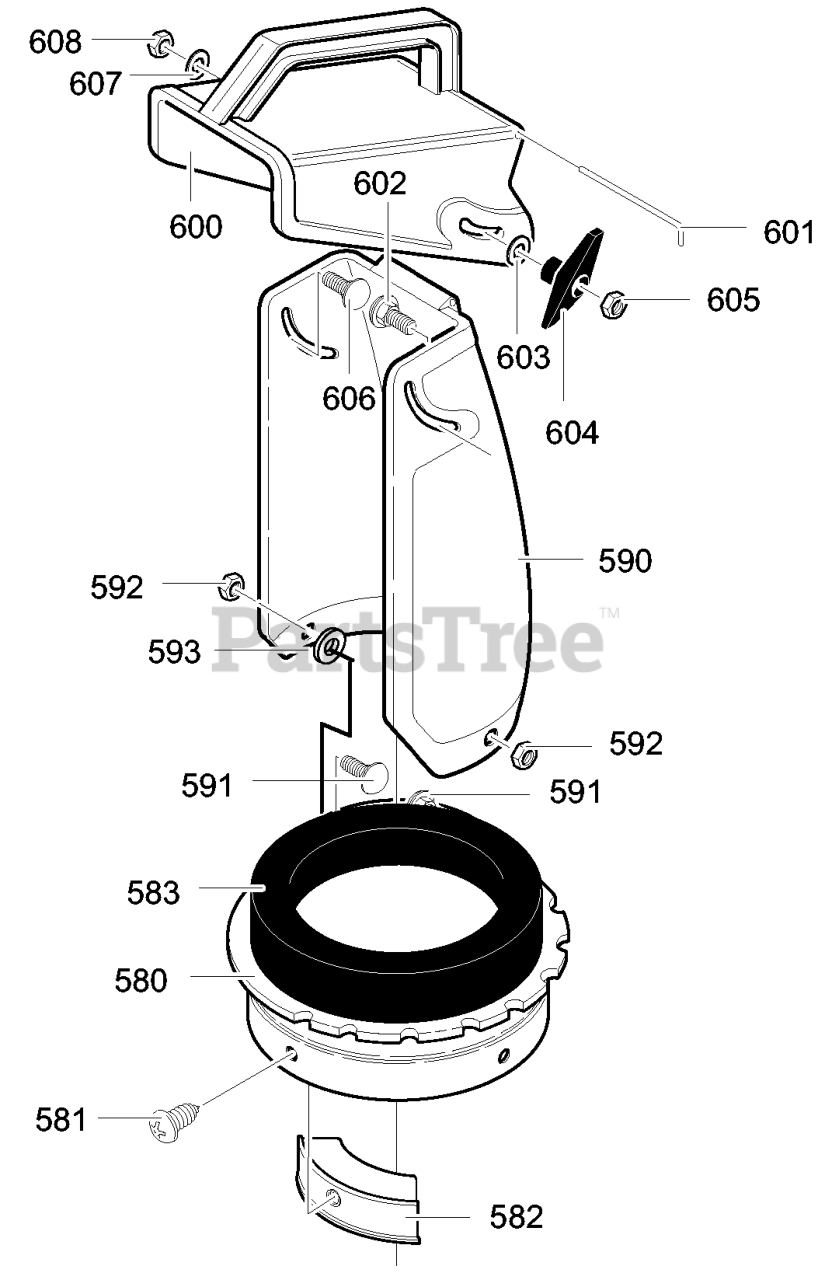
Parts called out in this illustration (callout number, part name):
580	RING, CHUTE
582	GUIDE, CHUTE
583	DONUT, FOAM
590	CHUTE, LOWER
591	SCREW, 1/4-20X .75
592	NUT, 1/4-20
593	WASHER, FLAT
600	CHUTE, UPPER WITH HANDLE
602	BOLT, 5/16-18X1.25
603	WASHER, FLAT
604	T-KNOB
605	NUT, 5/16-18
606	SCREW, 5/16-18
607	WASHER, FLAT
608	NUT, 5/16-18
